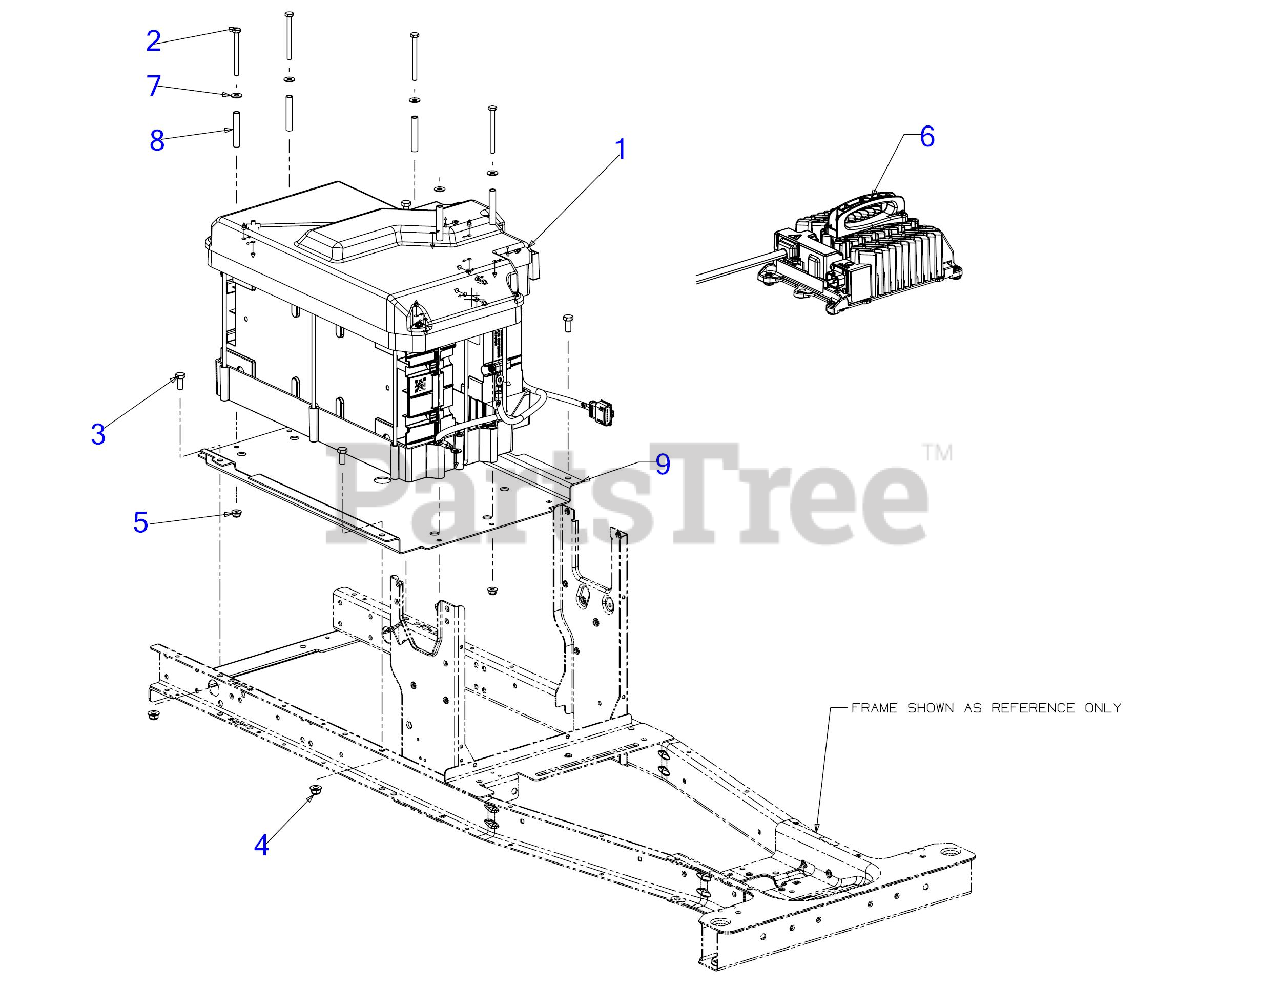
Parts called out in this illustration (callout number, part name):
1	BATTERY
2	SCREW 1/4-20 x 2.75 GR5
3	SCREW 5/16-18 x .75 GR5
4	FLANGE LOCK NUT 5/16-18
5	FLANGE LOCK NUT
6	CHARGER 48V 650W
7	FLAT WASHER
8	SPACER .259 X .375 X 2.120
